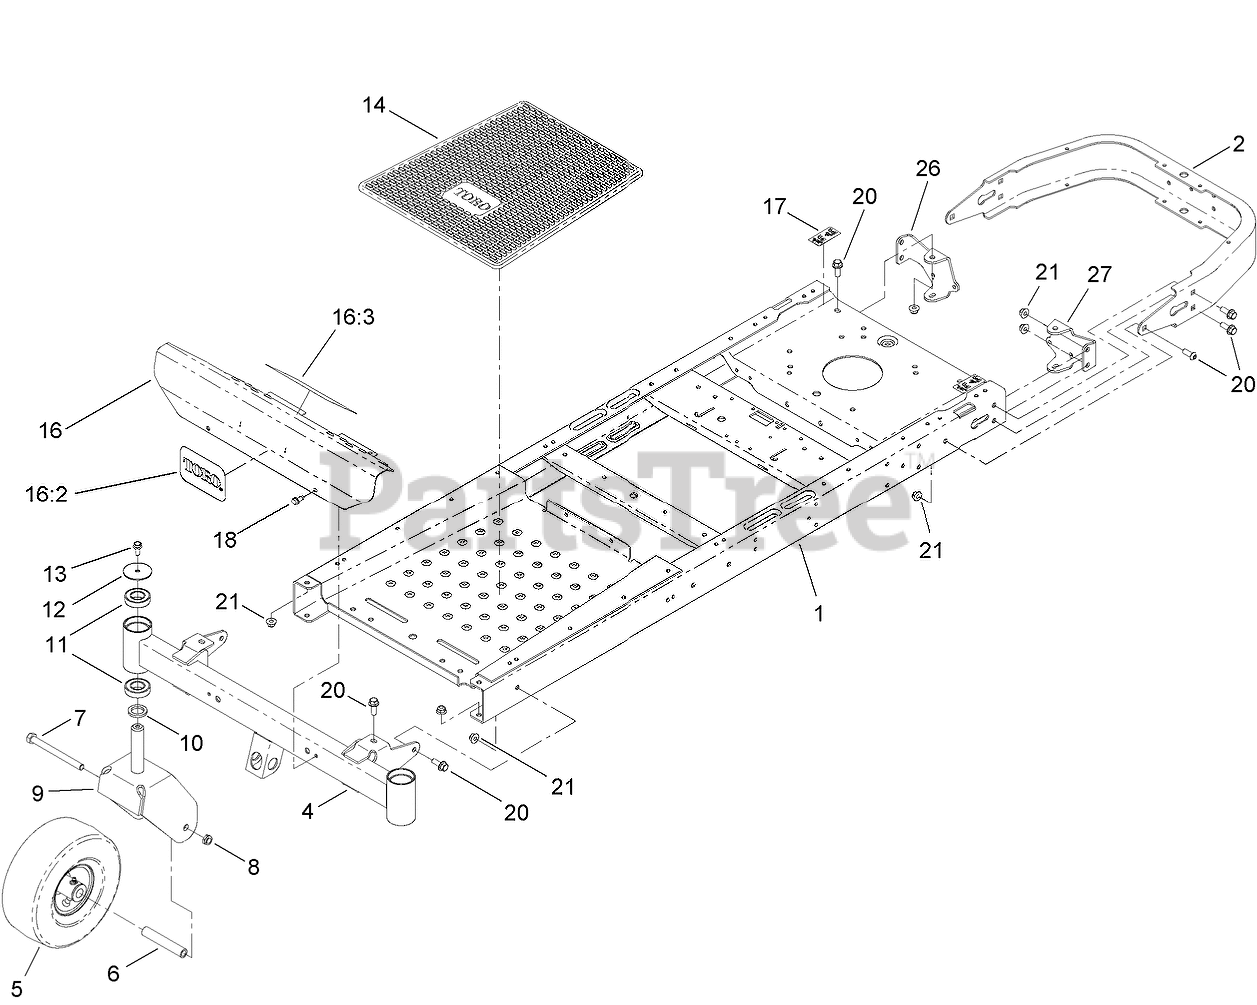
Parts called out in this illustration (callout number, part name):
2	BUMPER-REAR
4	AXLE-FRONT
5	CASTER WHEEL ASM (Cst)
6	BUSHING-SPANNER
7	SCREW-HH
8	NUT-LOCK, NI
9	FORK-CASTER
10	WASHER-THRUST
11	BEARING-BALL
12	WASHER
13	SCREW-HHF
14	MAT-FLOOR
16	FOOTREST ASM
16:3	DECAL-DANGER
17	DECAL-BYPASS
18	SCREW-HWHTF
20	SCREW-HHF
21	NUT-HF, NI
26	MOUNT-HYDRO, REAR (RH)
27	MOUNT-HYDRO, REAR (LH)
